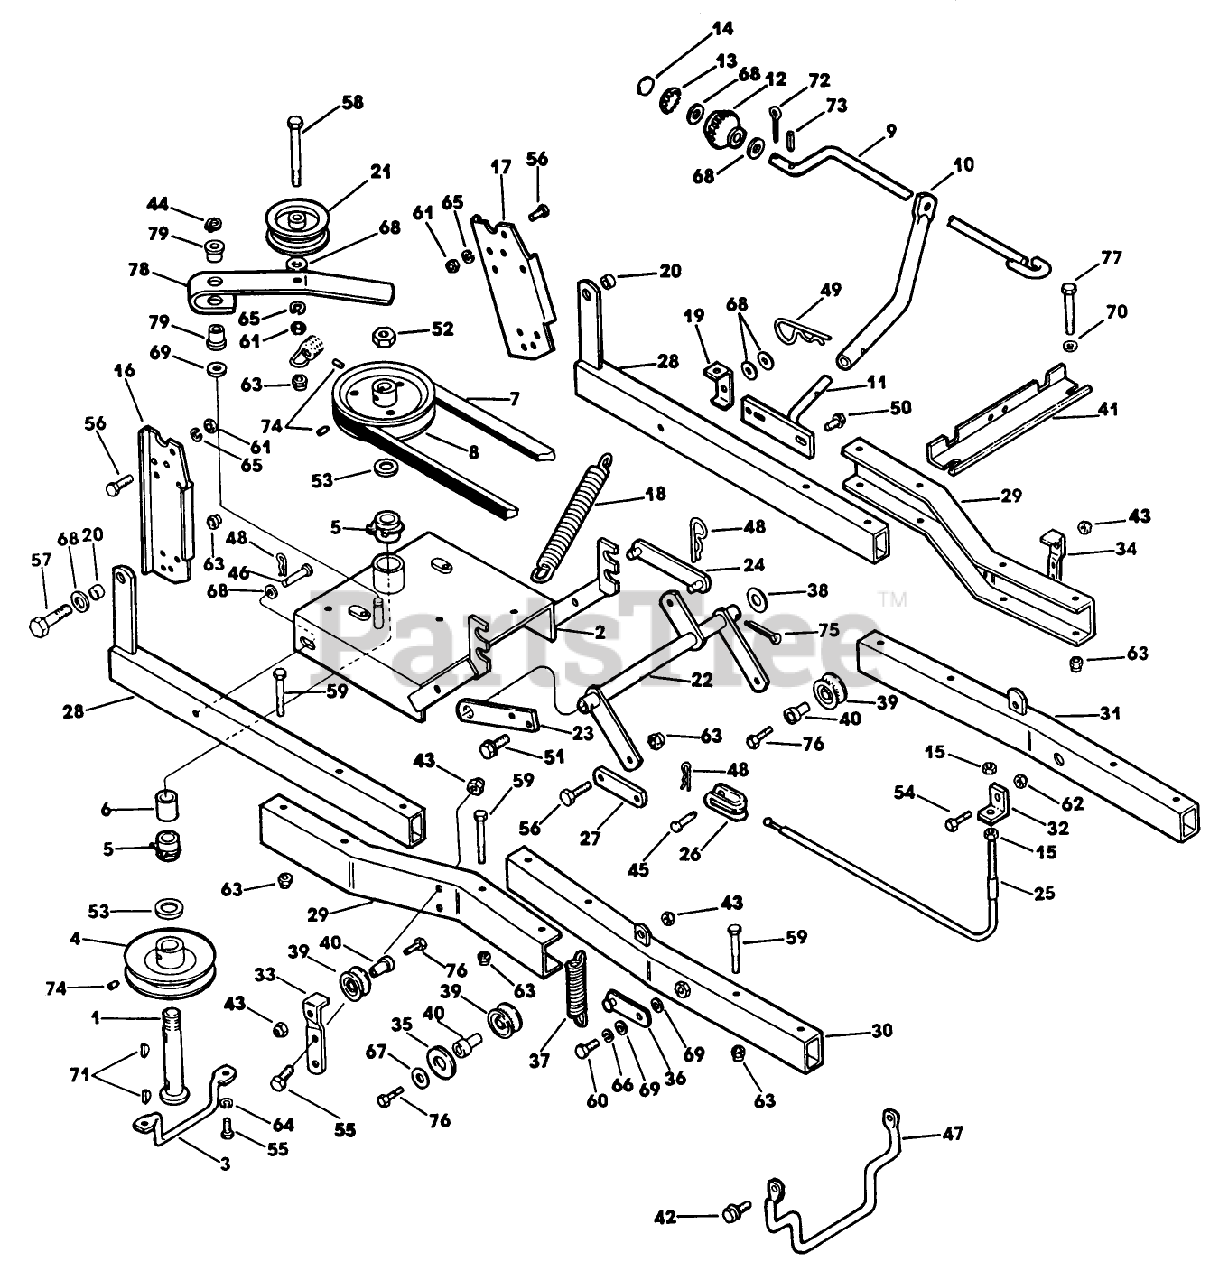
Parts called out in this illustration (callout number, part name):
1	SHAFT AY *NP
2	SUPPORT ASSY PULLY
7	V-BELT
10	TUBE-CRANK
12	KNOB
15	NUT SS
17	BRACKET MOUNTING
24	LIFT LINK
28	REAR FRAME AY
30	FRONT FRAME AY RH
42	SCREW-THREAD FRMG
43	NUT
44	SNAP RING
48	PIN - SPRING CLIP
53	WASHER-SHIM
55	SCREW - HEX
61	NUT
62	NUT-LOCK, CONE
63	NUT-LOCKING
65	WASHER
68	WASHER
70	WASHER
74	SET SCREW
79	BUSHING
